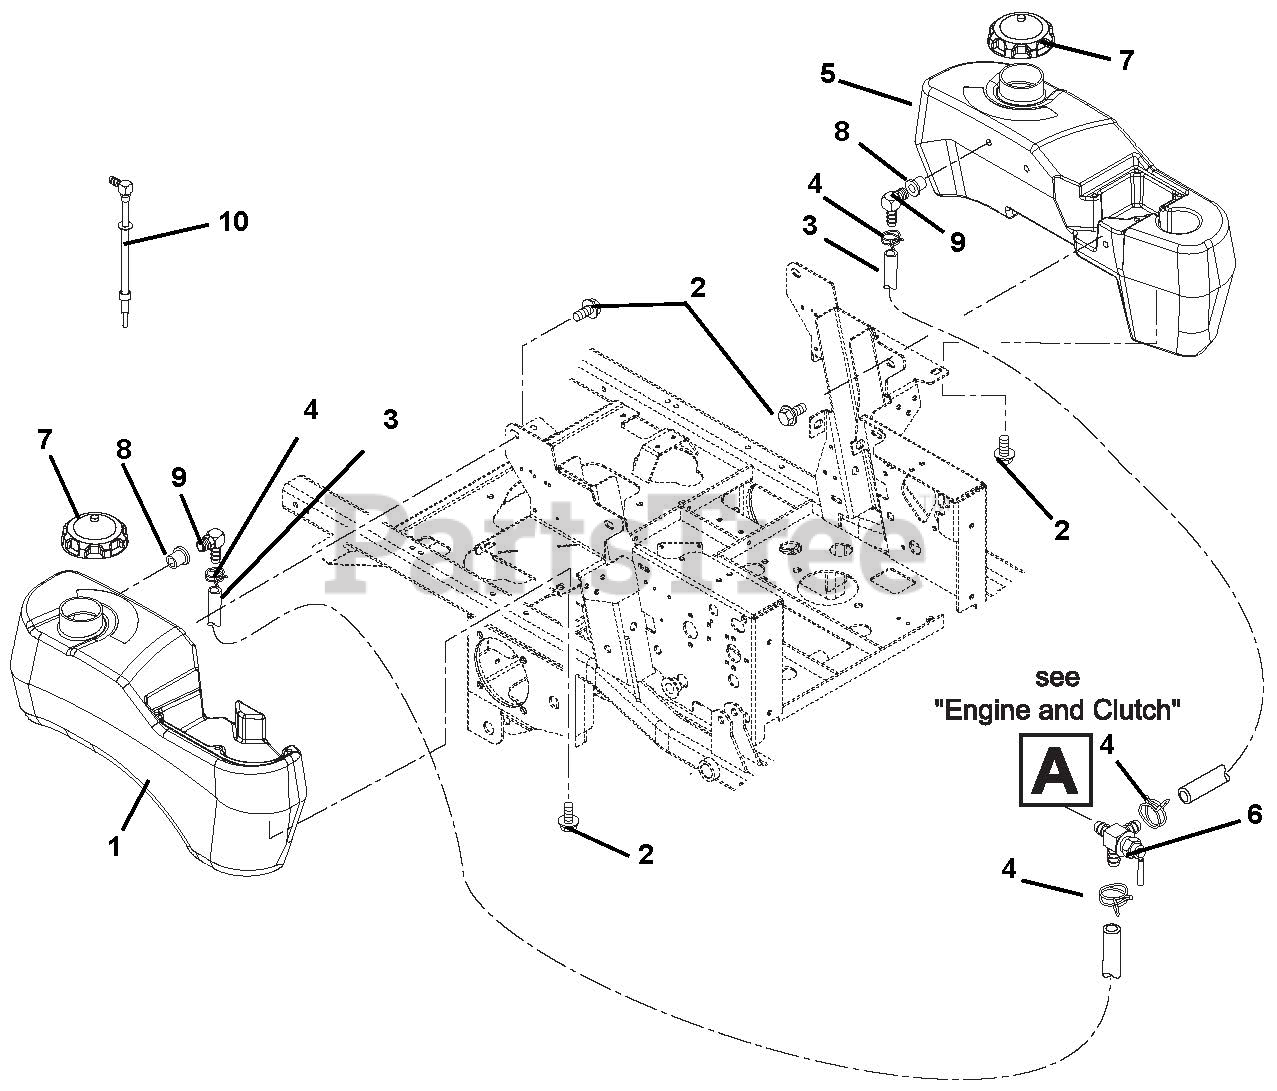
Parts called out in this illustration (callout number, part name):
1	Tank, Fuel - Right Hand
2	Bolt, SEMS .31-18 x .62
3	Hose, .25 Low-PERM Bulk Gas
4	Clamp, Fuel Line
5	Tank, Left Hand Fuel (EYE-Q)- 200 Series
6	Valve, Fuel
7	Cap, Gas
9	Tank Fitting
10	26" Fuel Line Kit, Gas
